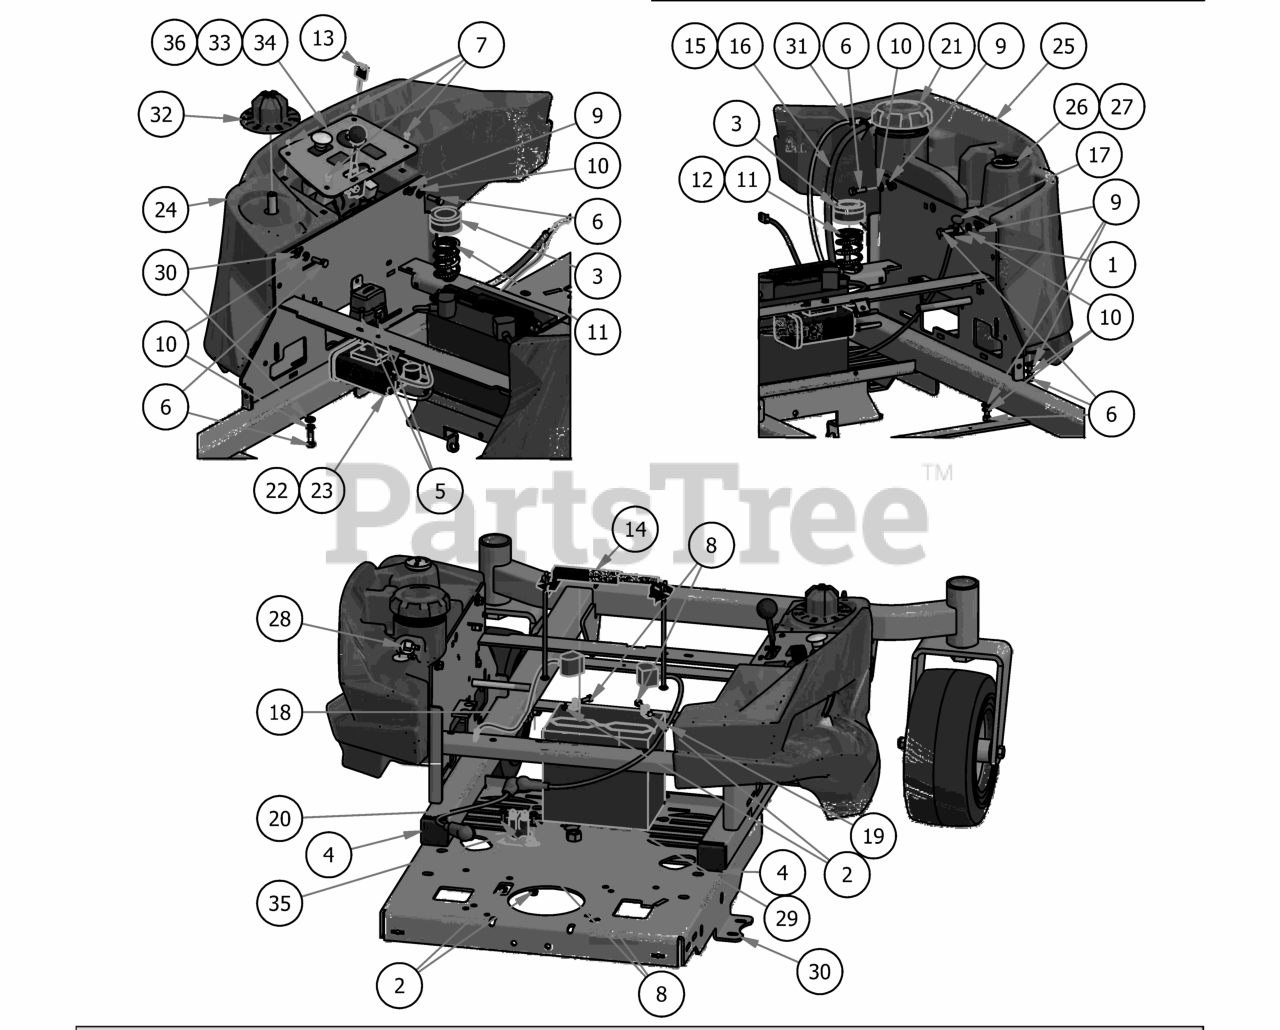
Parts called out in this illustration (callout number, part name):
1	3/8" Fine Threaded Jam Nut
2	1/4-20 Hex Flange Nuts Zinc w/Serrations
3	Seat Spring Cap Cover
4	2X2 Frame Plug
5	M6-1.0 X 16MM Hex Bolt
6	5/16" x 1" Bolt
7	10-32 x 3/8" Button Socket Head Bolt
8	1/4" x 3/4" Hex Bolt
9	5/16" Flat Washer
10	5/16" Lock Washer
11	Seat Spring Assembly (QTY 1 on Kawasaki Magnum)
12	Seat Spring Assy w/Cable (Kawasaki Magnum Only)
13	Ignition Key
14	Hold Down Assembly
15	15" Fuel Line Assembly (Kawasaki Engine)
16	37" Fuel Line Assembly (Kohler Engine)
18	Ground Cable
19	24" Red Battery Cable
20	12" Red Battery Cable
21	Tethered Fuel Tank Cap
22	MZ Kohler EPA Canister Assembly (Kohler KS-590 Only)
23	MZ Kohler EPA Canister Assembly
24	2017 MZ Right Gas Tank
25	2017 MZ Left Gas Tank
26	Fuel Gauge
27	Fuel Gauge Grommet
28	Rollover Valve
30	2017 MZ/ZT 42"-48" Frame
31	3/16 Vinyl Clamp
32	MZ/ZT Deck Height Dial
33	2017 Magnum Control Panel Assembly
34	2017 MZ Control Panel Assembly
36	Tach Wire (Only used with Magnum Control Panel)
